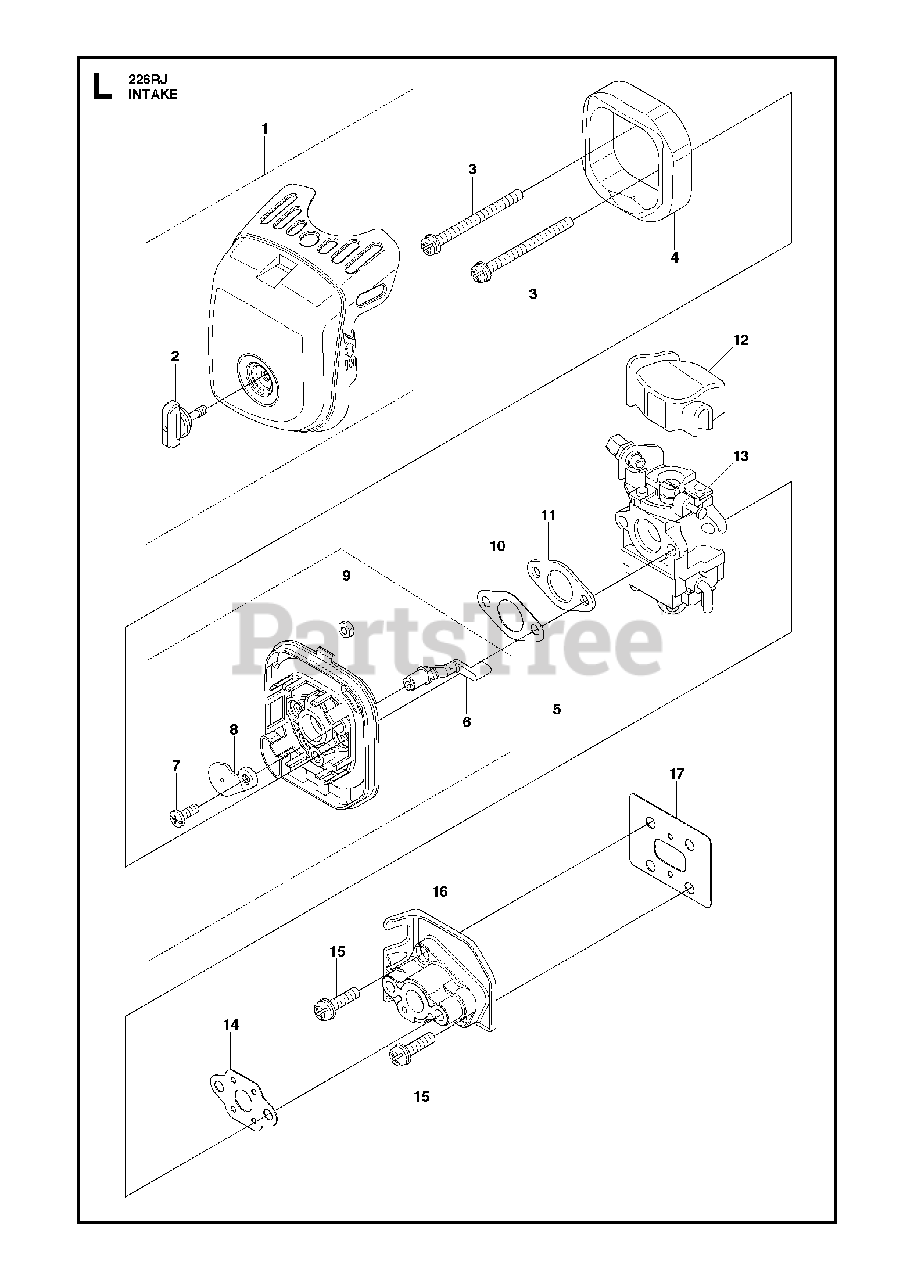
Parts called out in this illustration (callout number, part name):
2	KNOB
6	LEVER
7	SCREW
8	Choke Plate
9	SLEEVE
13	Carburetor
